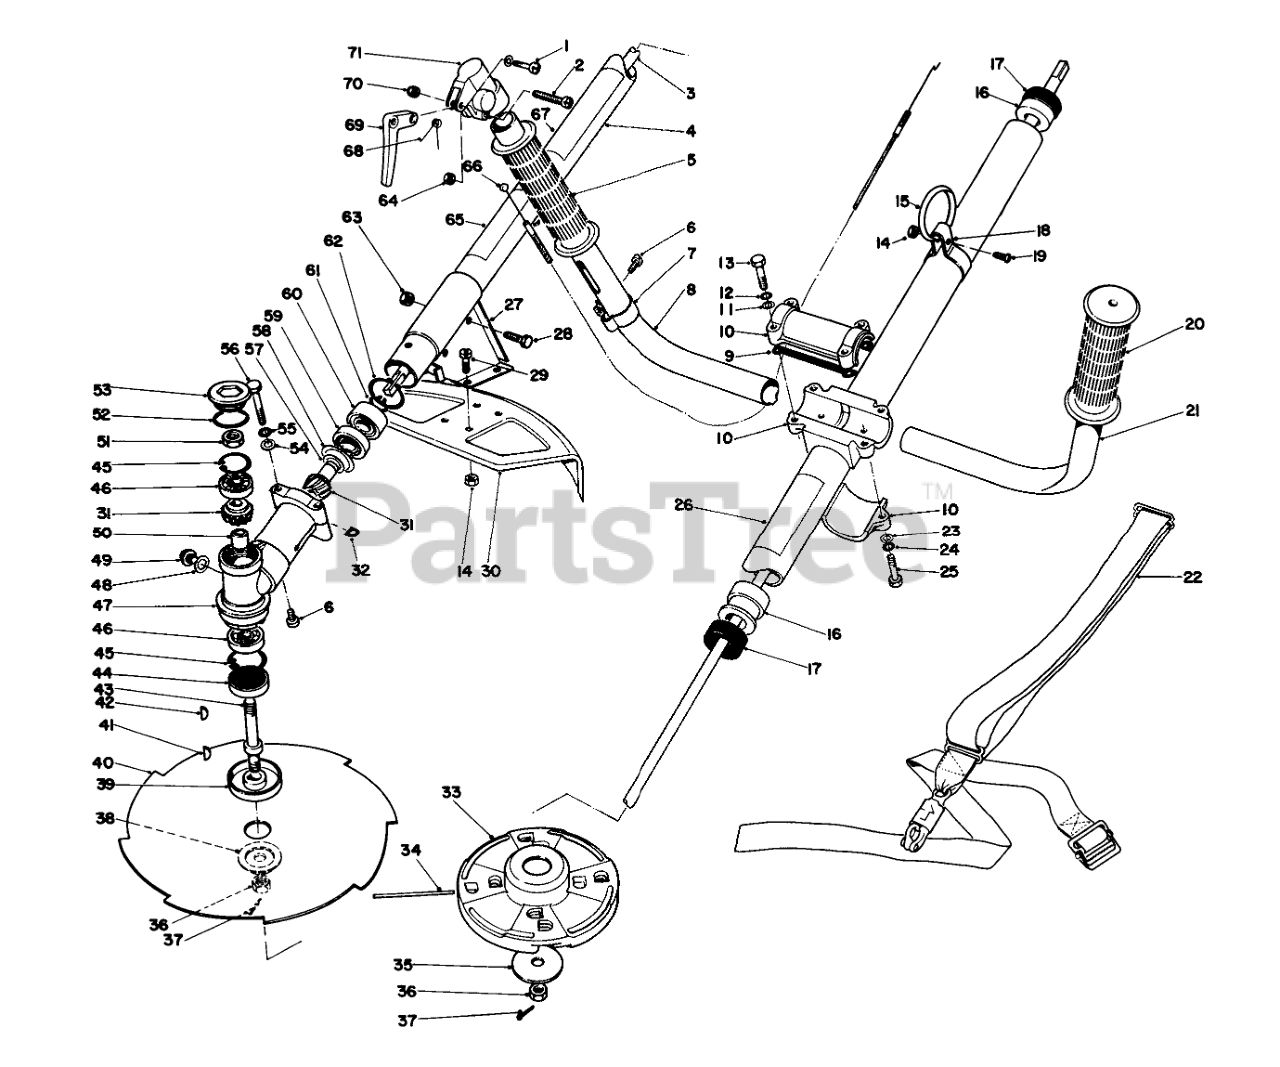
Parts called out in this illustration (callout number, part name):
1	Screw
2	Screw w/Washer
3	Shaft-Driving
4	Housing Drive Shaft (Incl. Ref. #26 & 27)
5	Right Hand Grip
6	SCREW
8	Handle R.H.
9	Shim Washer
10	Bracket Assembly, Handle (Incl. Ref. #26 & 27)
11	WASHER
12	Washer
14	NUT-LOCK, NI
15	RING-HARNESS
17	Bushing
18	HARNESS CLAMP
19	SCREW-SRH
20	LH GRIP
21	Handle L.H.
22	Deluxe Harness
23	Washer
24	Washer
26	Decal
27	Bracket Shield
28	SCREW-HH
29	SCREW-PPH
30	Shield
31	Gear Set
32	Spacer
33	FIXED LINE CUTTER HD PK
34	LINE PACK (100)
35	Washer
37	1/16 X 1 LG COTTER PIN
38	Blade Adapter Kit (Incl. Ref. #36 & 37)
39	Plate-Blade Fixing
40	Weed Blade
41	Woodruff Key
42	Woodruff Key
43	Shaft, Power Take Off
44	Oil Seal
45	Circlip
46	Ball Bearing
47	Housing Gear
48	Gasket
50	Spacer
52	O-Ring
53	Lid, Gear Housing
54	WASHER
55	Washer
57	Washer
58	Washer
59	Ball Bearing
60	Ball Bearing
61	Circlip
62	Circlip
63	NUT-LOCK, NI
64	Nut
65	Decal-TC800
66	Throttle Cable
67	Decal Warning
68	Return Spring
69	THROTTLE LEVER
71	Bracket-Throttle Trigger
